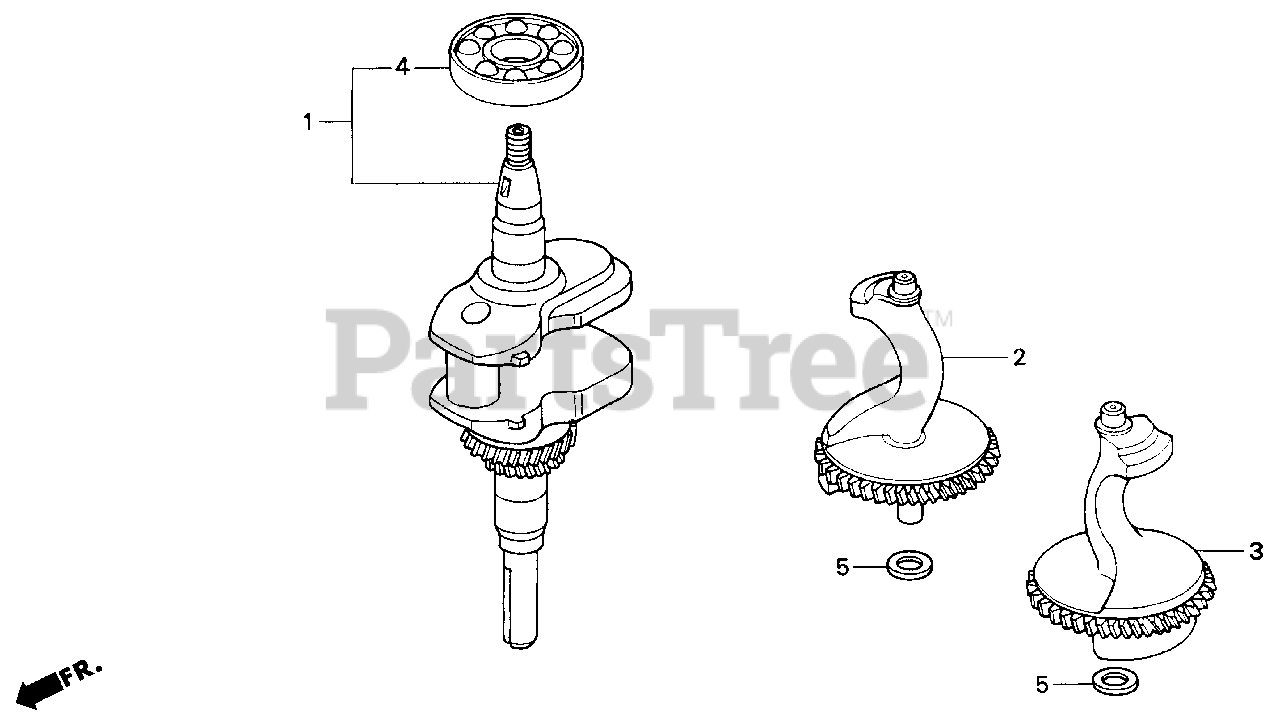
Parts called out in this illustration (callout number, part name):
1	CRANKSHAFT
2	WEIGHT A, BALANCER
3	WEIGHT B, BALANCER
4	BEARING, RADIAL BALL (6207)
5	WASHER, THRUST (14MM)
